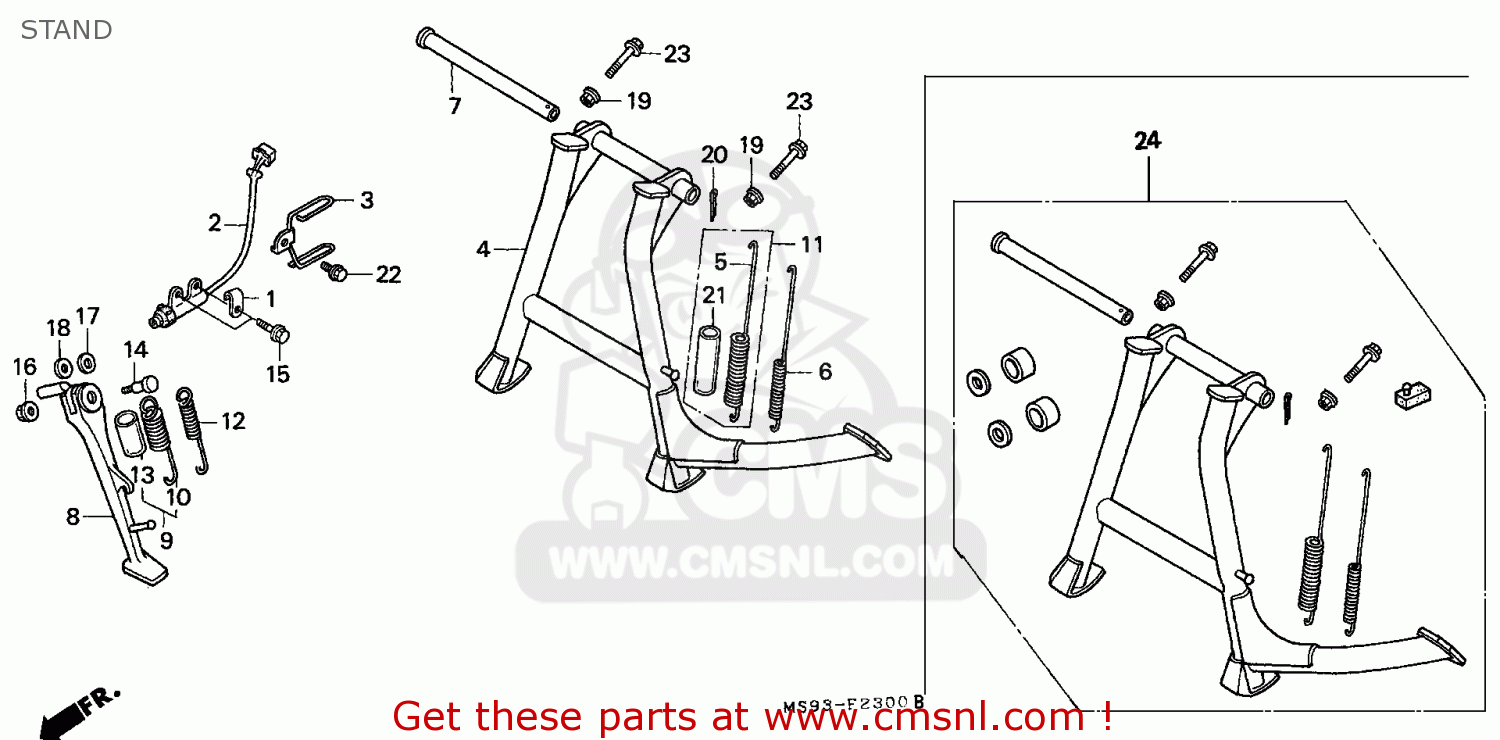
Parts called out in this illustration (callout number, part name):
1	CLIP,PULSER CORD.
2	SWITCH ASSY.,SIDE
3	GUIDE,DRAIN TUBE
4	STAND COMP.,MAIN
5	SPRING,MAIN STAND
7	PIPE,MAIN STAND P
8	BAR,SIDE STAND
10	SPRING,SIDE STAND
13	TUBE,SIDE STAND S
14	BOLT,SIDE STAND P
15	BOLT,FLANGE,6X16
16	NUT,SIDE STAND
17	WASHER,TRST,24X13
18	WASHER,TRST,24X10
19	NUT,FLANGE,8MM
20	PIN COTTER 2.5MM
21	TUBE,VINYL,17.5X2
22	BOLT,FLANGE,6X10
23	BOLT,FLANGE,8X40
